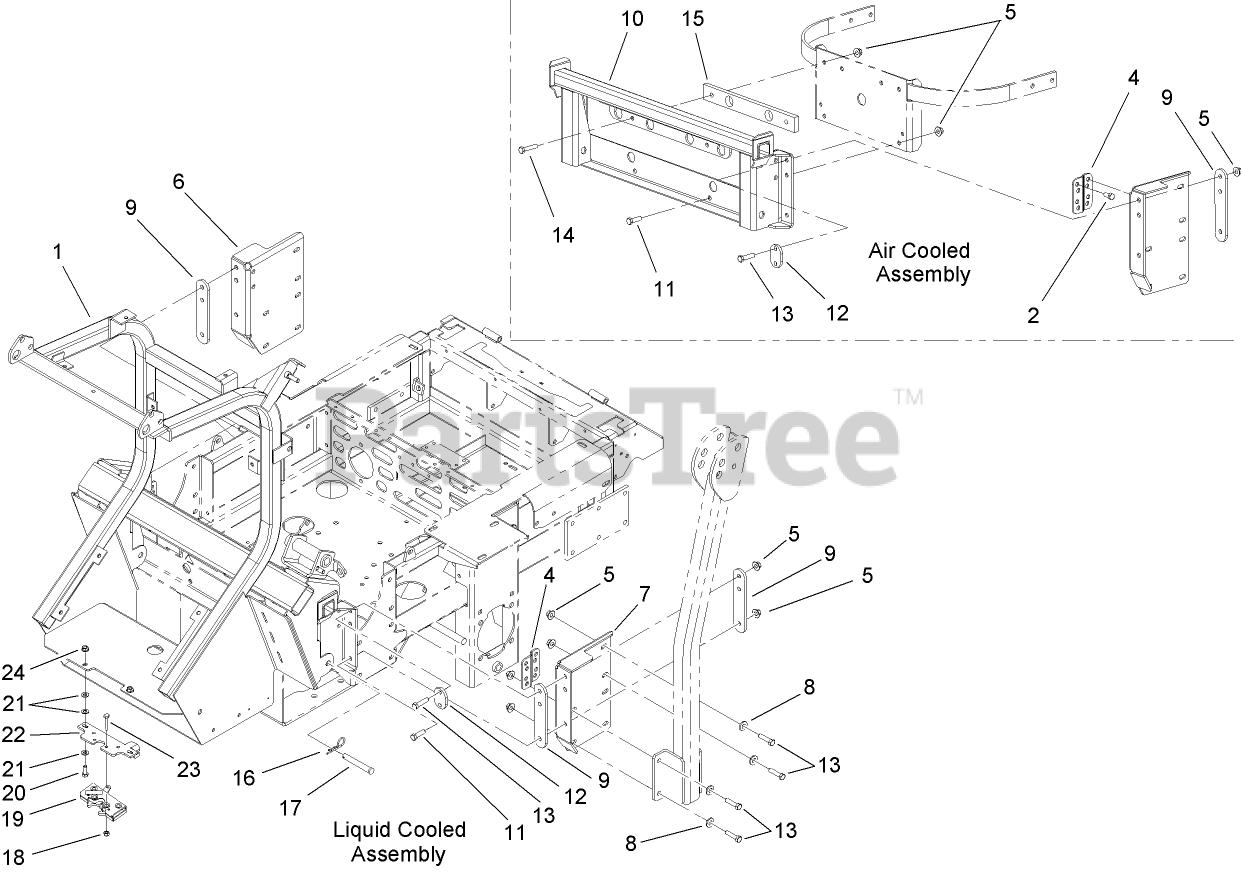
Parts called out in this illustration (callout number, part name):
1	HOPPER FRAME ASM
2	SCREW-HH
4	BRACKET-STIFFENER
5	NUT-HF
6	SUPPORT-BAGGER, LH
7	SUPPORT-BAGGER, RH
8	WASHER-BELLEVILLE
9	SPACER-FRAME
10	BAGGER MOUNT ASM
11	SCREW-HH
12	SPACER-FRAME, SHORT
13	SCREW-HH
14	SCREW-HH
15	SPACER-FRAME, BAGGER
16	PIN-COTTER
17	PIN-CLEVIS
18	NUT-LOCK, NI
19	LATCH-ROTOR
20	SCREW-HH
21	WASHER-PLAIN
22	BRACKET-LATCH
23	SCREW-HH
24	NUT-HF
